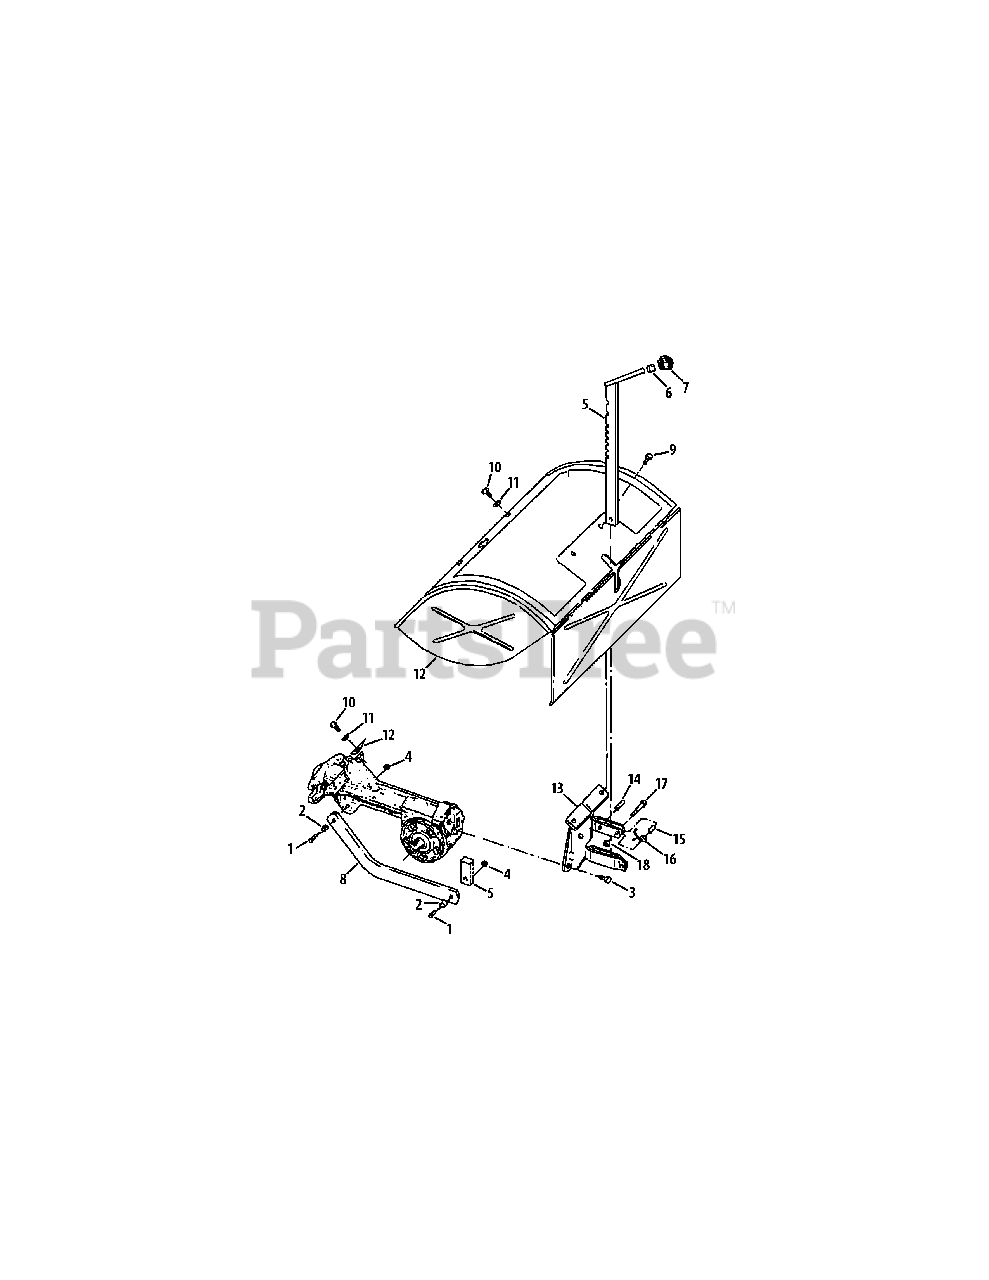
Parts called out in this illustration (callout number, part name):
1	Hex Bolt, 3/8"-16 x 1-1/4"
2	Bushing Spacer, .5 x .375 x .3
3	Hex Flange Bolt, 5/16"-18 x .625
4	Flangelock Nut, 3/8"-16
5	Depth Regulator
6	Retaining Ring
7	Depth Regulator Knob
8	Depth Regulator Bar Drag
9	Thread-forming Screw, 1/4"-20 x 1/2"
10	Hex Flange Bolt, 5/16"-18
11	Washer, 1.12 x .34 x .06
13	Hood Bracket
14	Roll Pin (Spirol), 1/4" x 1"
15	Split Spacer
17	Hex Bolt, 1/4"-20 x 1"
18	Locknut, 1/4"-20
